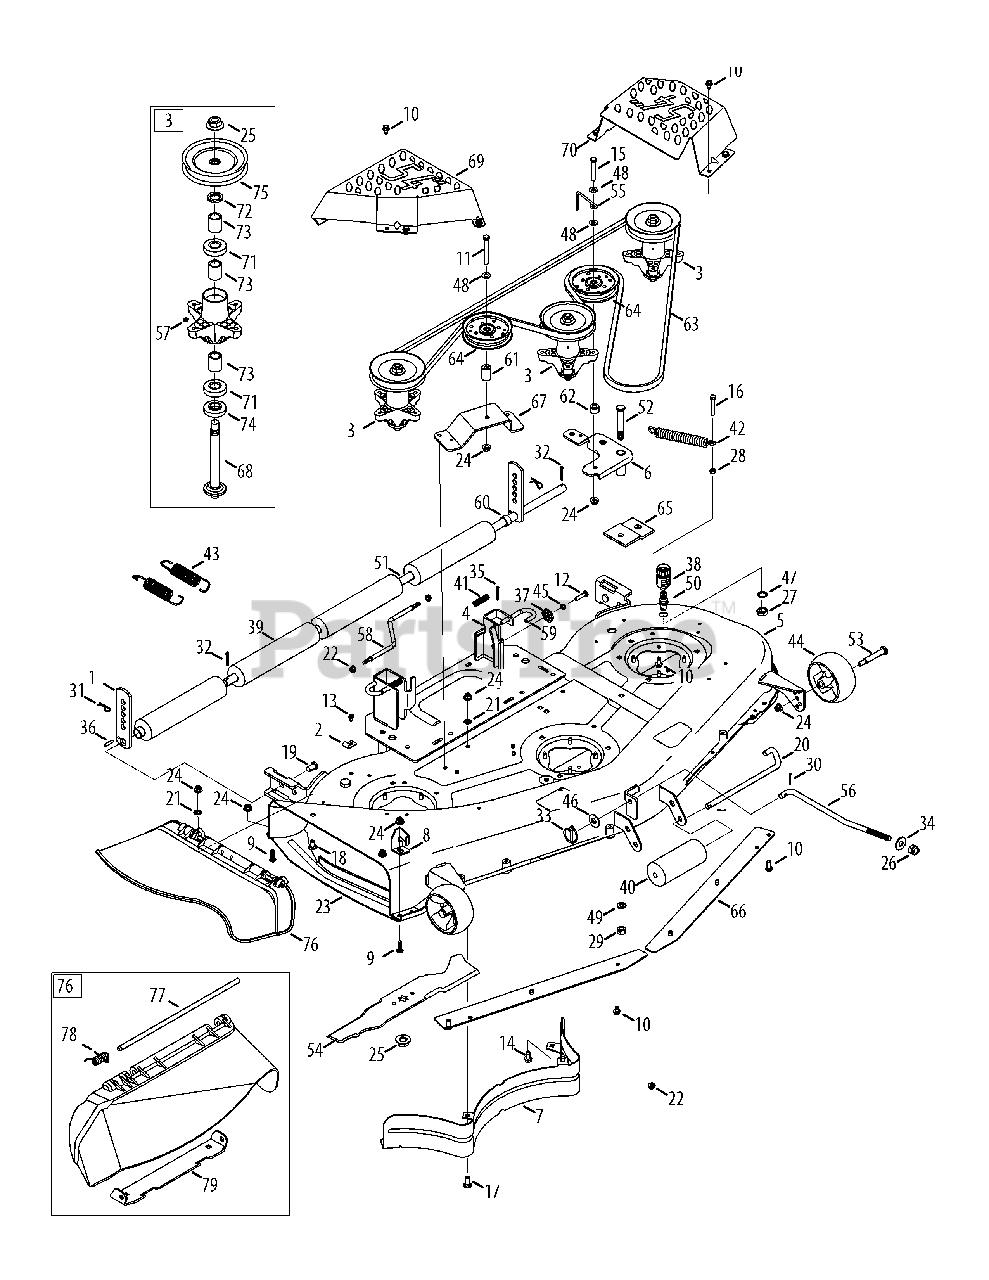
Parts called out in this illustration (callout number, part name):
2	Retainer Hook Brkt.
3	Spindle Assembly
5	54" Deck
6	Idler Assembly
7	RR Inner Baffle
8	Chute Stop Deflector
9	Screw, 3/8-16 x 1.0
10	S-Tapp Screw 5/16-18 x .75
11	Screw, 3/8-16 x 3.0
12	Hex Bolt 5/16-18 x 1.25
13	Hex Screw 1/4-20 x .50
14	Screw, 3/8-16 x 0.75
15	Screw, 3/8-16 x 2.5
16	Hex Hd Cap Screw. 5/16-18 x 2.0 Gr. 5
17	Carriage Bolt 3/8-16 x 1.0
18	Short Neck Carriage Bolt 3/8-16 x .75
19	Clevis Pin .50 Dia. x .78
20	Roller Pin .5" Dia x 7.31
21	Push Nut 3/8
22	Flange Locknut 5/16-18 Gr. F, Nylon
23	Fin ger Guard
24	Flange Lock-Nut 3/8-16 Gr. F Nylon
25	Hex Flange Nut 5/8-18
26	Flexlock Nut, 1/2-13
27	Hex Nut, M16-1.5
28	Hex Nut 5/16-18 hd. (Gr. 5)
29	Hex L-Nut 1/2-13
30	Cotter Pin 3/32 x 1.0
31	Cotter Pin
32	Cotter Pin
33	Linch Pin .1875
34	Washer .63 x 1.25 x .180
35	Cotter Pin 1/8" Dia x 1.25
36	Spring Pin 1/4 Dia. x 1.0
37	Deck adjustment Gear
38	Water Nozzle Adaptor
39	Deck Roller
40	Front Roller
41	Compression Spring .535 OD x 1.751 Lg.
42	Extension Spring .85 Dia. x 5.915
43	Extension Spring 1.5 x 5.99
44	Deck Wheel 5.0
45	L-Wash 5/16 ID
46	Flat Washer .531 x 1.25 x .100
47	Lockwasher 5/8
48	Flat Washer .406 x .875 x .059
49	Lockwasher
50	Port, Water
51	Shaft .75 x 47.12
52	Shoulder Screw
53	Shoulder Screw
54	Blade 18.5"
55	Idler Belt Keeper Rod
56	Deck Lift Rod
57	Grease
58	Deck Sway Rod
59	Deck Release Pin
60	Spacer .82 ID x 1.0 OD x .53
61	Spacer .380 ID x .90 OD x 1.313
62	Spacer .385 ID x .88 OD x .64
63	V-Type Belt
64	Idler Pulley w/Flange 4.25 Dia
65	Bracket, Stabilizing
66	Deck Shirt
67	Idler Bracket
68	Spindle Shaft, 6.95" Lg.
69	Spindle Cover RH
70	Spindle Cover LH
71	Ball Bearing .787 ID x 1.85 OD x .551
72	Spacer .790 ID x 1.25 OD x .175
73	Spacer .79 x 1.82 x .55
74	Spacer .79 ID x 1.82 OD x .55
75	Deck Pulley
76	Chute Assembly
77	Hinge Pin
78	Torsion Spring .44 ID x 2.0
79	Chute Bracket
